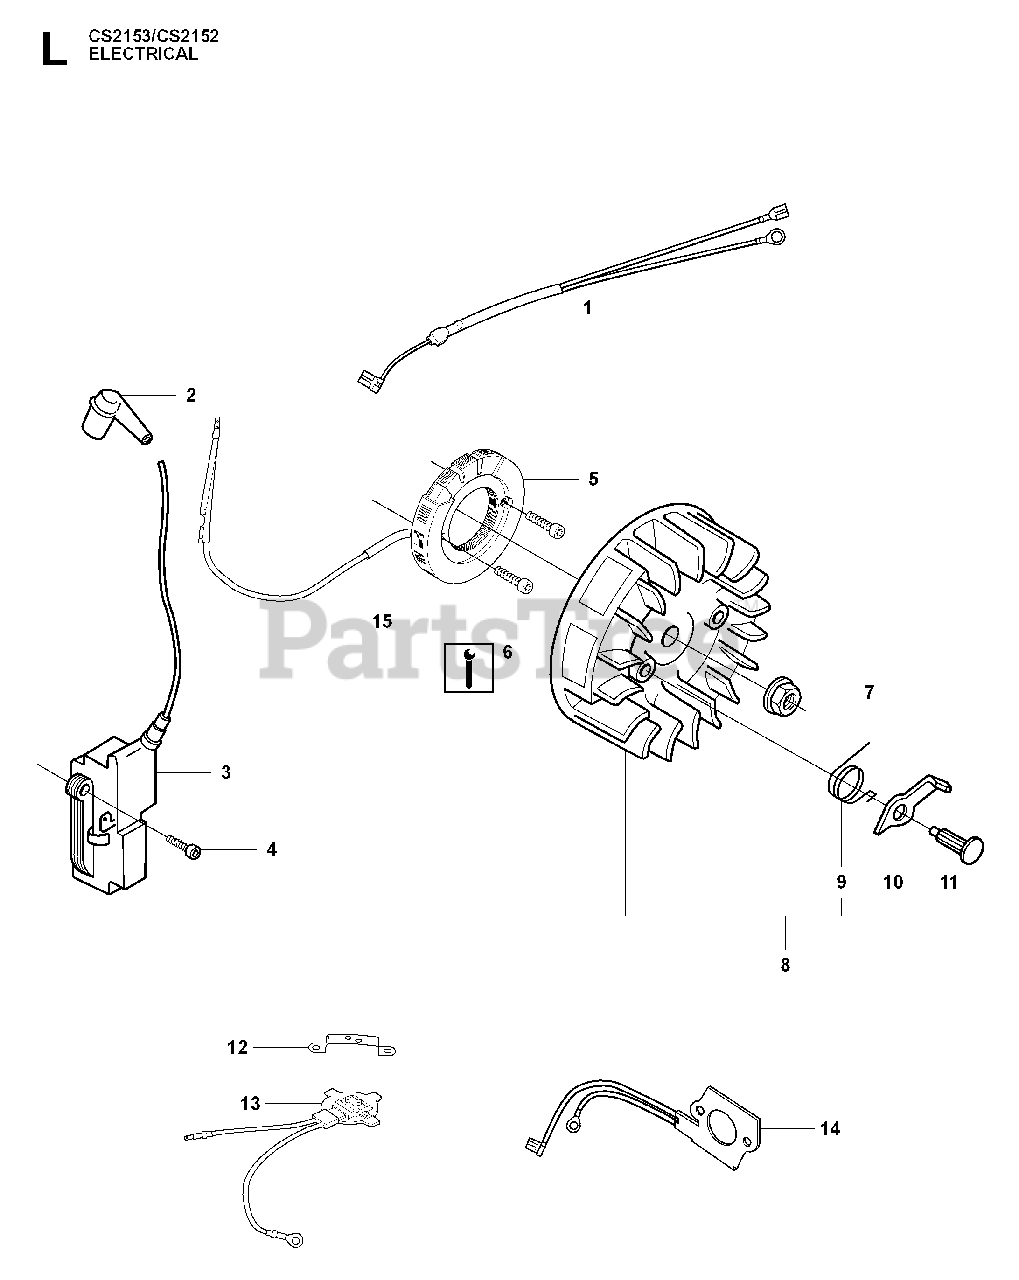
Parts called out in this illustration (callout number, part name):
1	WIRING ASSY
1	WIRING ASSEMBLY
2	SPARK PLUG CONN. KIT
3	IGNITION MODULE
3	%IGNITION MODULE
5	GENERATOR
5	GENERATOR STATOR
7	NUT W/ WASHER
8	FLYWHEEL (G)
8	FLYWHEEL
9	%SPRING, STARTER CATCH
13	THERMOSTAT ASSY
14	HEATING PLATE
15	CABLE COVER
